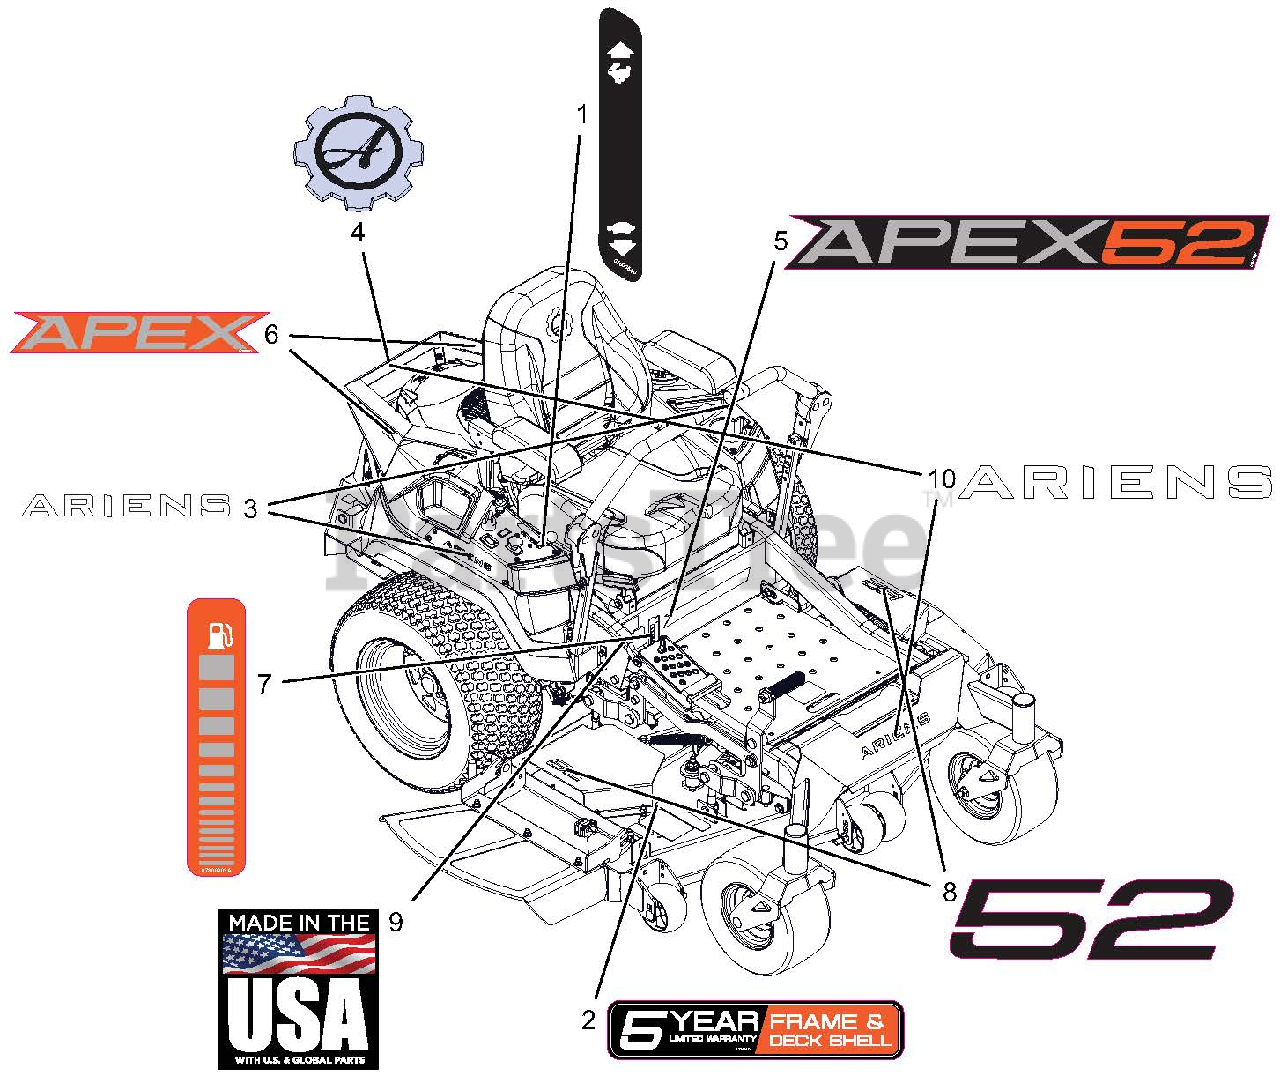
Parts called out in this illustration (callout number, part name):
1	DECAL, DASH DECAL
2	DECAL, DECK 5 YEAR-ARIENS
3	DECAL, ARIENS (6.50")
4	DECAL, ARIENS-GEAR BADGE -THK
5	DECAL, 52" APEX KICKPLATE
6	DECAL, APEX FENDER
7	DECAL, ARIENS FUEL LEVEL
8	DECAL, BLACK 52
9	DECAL, MADE IN USA
10	DECAL - ARIENS 9.625"
